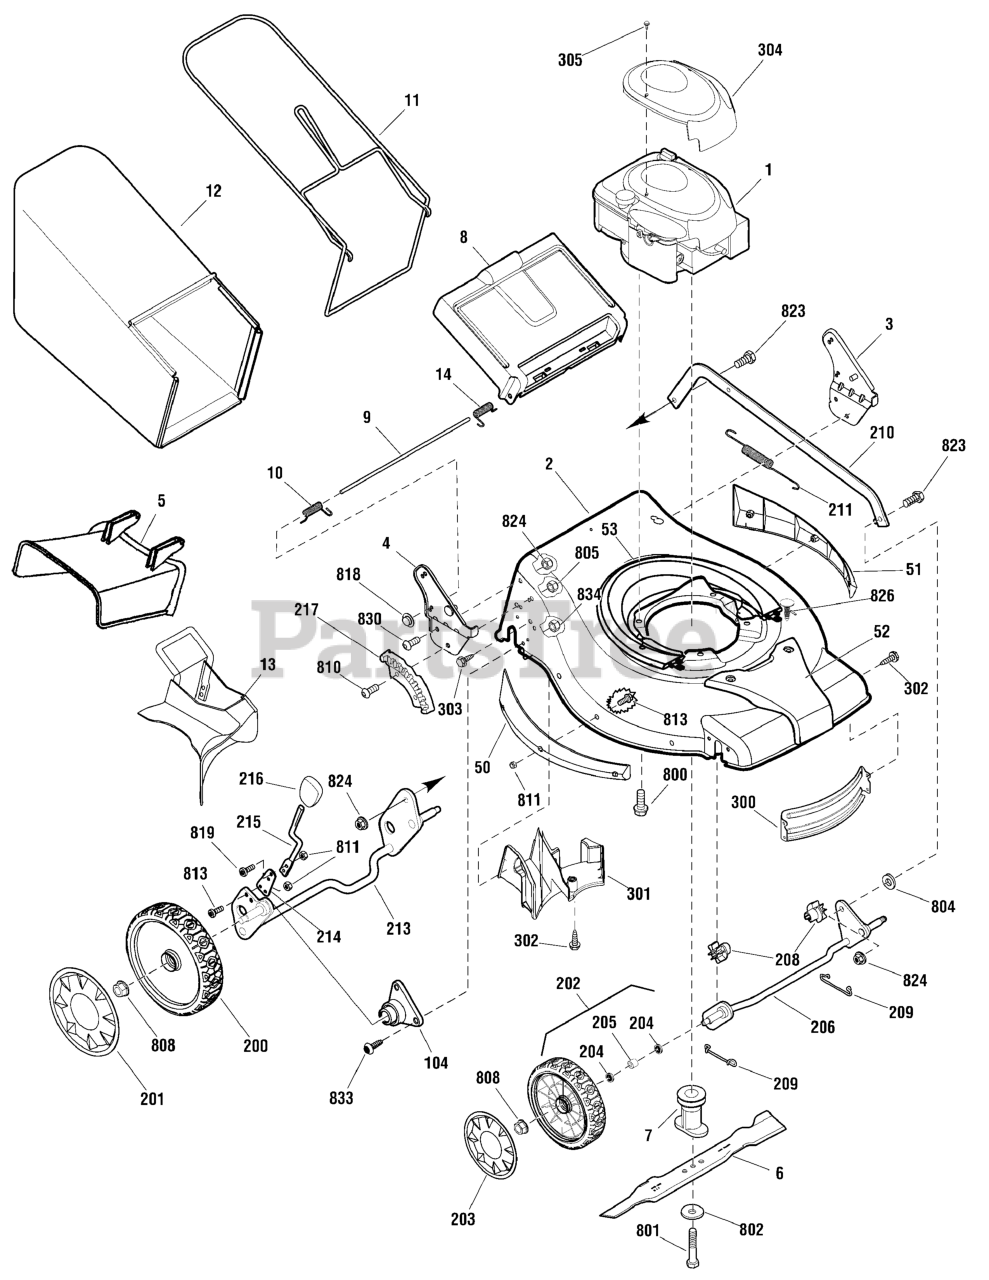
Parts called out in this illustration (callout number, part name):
1	* ENGINE, B&S, 550 Series, 10L802-0115-F1
2	HOUSING ASSEMBLY, 19" SD
3	BRACKET ASSEMBLY, Left Handle
4	BRACKET ASSEMBLY, Right Handle
5	DEFLECTOR, Chute
6	BLADE, 19"
7	BLADE ADAPTER ASSEMBLY
8	DOOR, Rear
9	ROD, Rear Door
10	SPRING, Torsion Rear Door, Right
11	FRAME ASSEMBLY
12	BAG ASSEMBLY
13	MULCH PLUG
14	SPRING, Torsion Rear Door, Left
50	SIDE GUARD, Right
51	SIDE GUARD, Left
52	HOUSING COVER, Front
53	HOUSING COVER, Rear
104	SLEEVE ASSEMBLY, Rear Axle
200	WHEEL, Rear
201	HUBCAP, Rear
202	WHEEL, Front, Complete
203	HUBCAP, Front
204	WHEEL BEARING
205	SPACER
206	CROSSBAR ASSEMBLY, Front
208	BUSHING, Front Crossbar
209	SPRING, Clip Crossbar
210	LINK, Single Lever
211	SPRING, Extension
213	REAR CROSSBAR
214	SPRING, Adjuster
215	LEVER, Height Adjustment
216	KNOB, Adjuster
217	BRACKET, Height Adjuster
300	BAFFLE, Front
301	BAFFLE, Rear
302	SCREW, Pan Head, Taptite, 1/4-20 x 1/2
303	SCREW, 1/4-15 x 5/8
304	SHROUD, With Label
305	SCREW, Machine Hex Washer Head
800	SCREW, HWST, 3/8 C X1 BZ
801	BOLT, 3/8-24 x 2 Gr. 8
802	WASHER, Belleville 7/16 ID
804	WASHER, 5/8
805	NUT, Nylock, M8 x 1-1/4
808	NUT, Flange Lock 3/8-16
810	BOLT, Hex Key Head
811	NUT, Nylock
813	SCREW, Torx Head, M5 x 0.8 x 14mm
818	NUT, Push, 1/4 BZ
819	SCREW, Torx Head, M5 x 0.8 x 12.5mm
823	BOLT, Hex Washer Head Shoulder, 5/16-18
824	NUT, 5/16-18, Flange Lock, BZ
826	SCREW, Truss Head Torx, 1/4-20 x 7/8
830	SCREW, 5/16-18 x 1.1, Hex Washer
833	SCREW, Torx, 1/4-20 x 5/8
834	NUT, Flange Lock, 1/4-20
